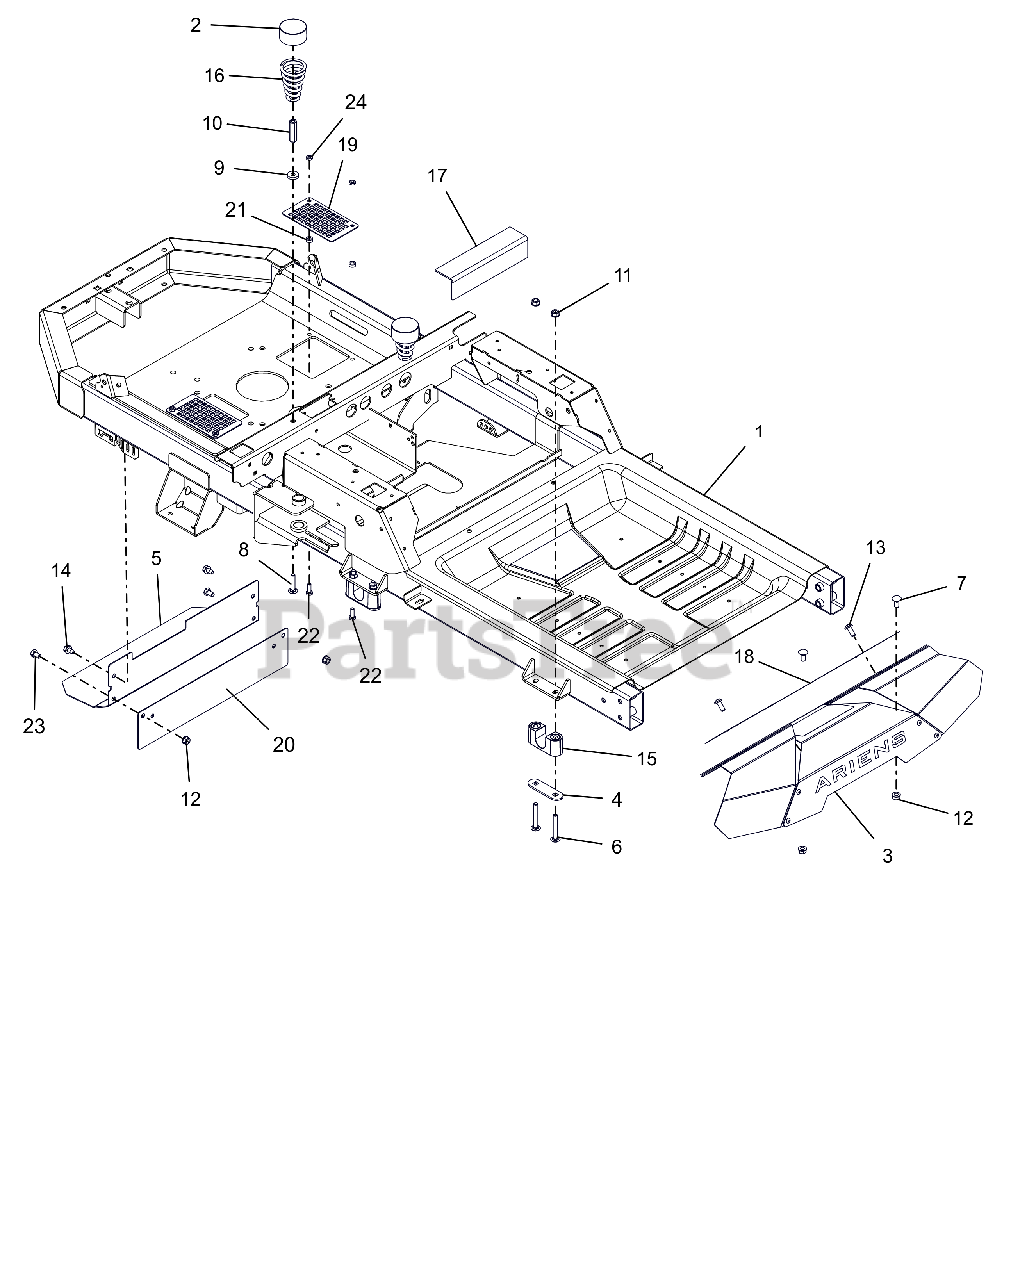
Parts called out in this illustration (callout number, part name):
1	KIT, IKON-X/XL FRAME (2016)
2	HUB CAP
3	KIT, IKON FOOT REST W/DECAL
4	PLATE, BEARING SUPPORT
5	HEAT, SHIELD
6	BLT, RHSSN.31-18X2.25 G5 ZCC
7	BLT,RHSN .31-18X.75 G5 ZCC
8	BLT,RHSN .31-18X1.50 G5 ZCC
9	WSHR, FLT .328X.870X.179 ZCC
10	NUT, COUPLING .31-18X1.75 ZCC
11	NUT,LK-CTR-FLG .31-18 GF ZCC
12	NUT-LK-TOP-FLG .312-18 GF ZCC
13	SCR-RDHDSKTAP .31-18 X .75
14	SCR,TAP .312-18X.50 HWH TR ZCC
15	BSHG, DECK LIFT PIVOT
16	SPRING, SEAT
17	PAD, RUBBER-TANK
18	GRIP TAPE, FOOT PLATE
19	GUARD, VENT
20	GUARD, REAR CLUTCH
21	BSHG-SLV .265X.500X.219
22	BLT, HEX .25-20X.75 G5 ZCC
23	BLT, HEX .31-18X.50 GR5 ZCC
24	NUT-LK-CTR-JAM .250-20 GB ZCC
